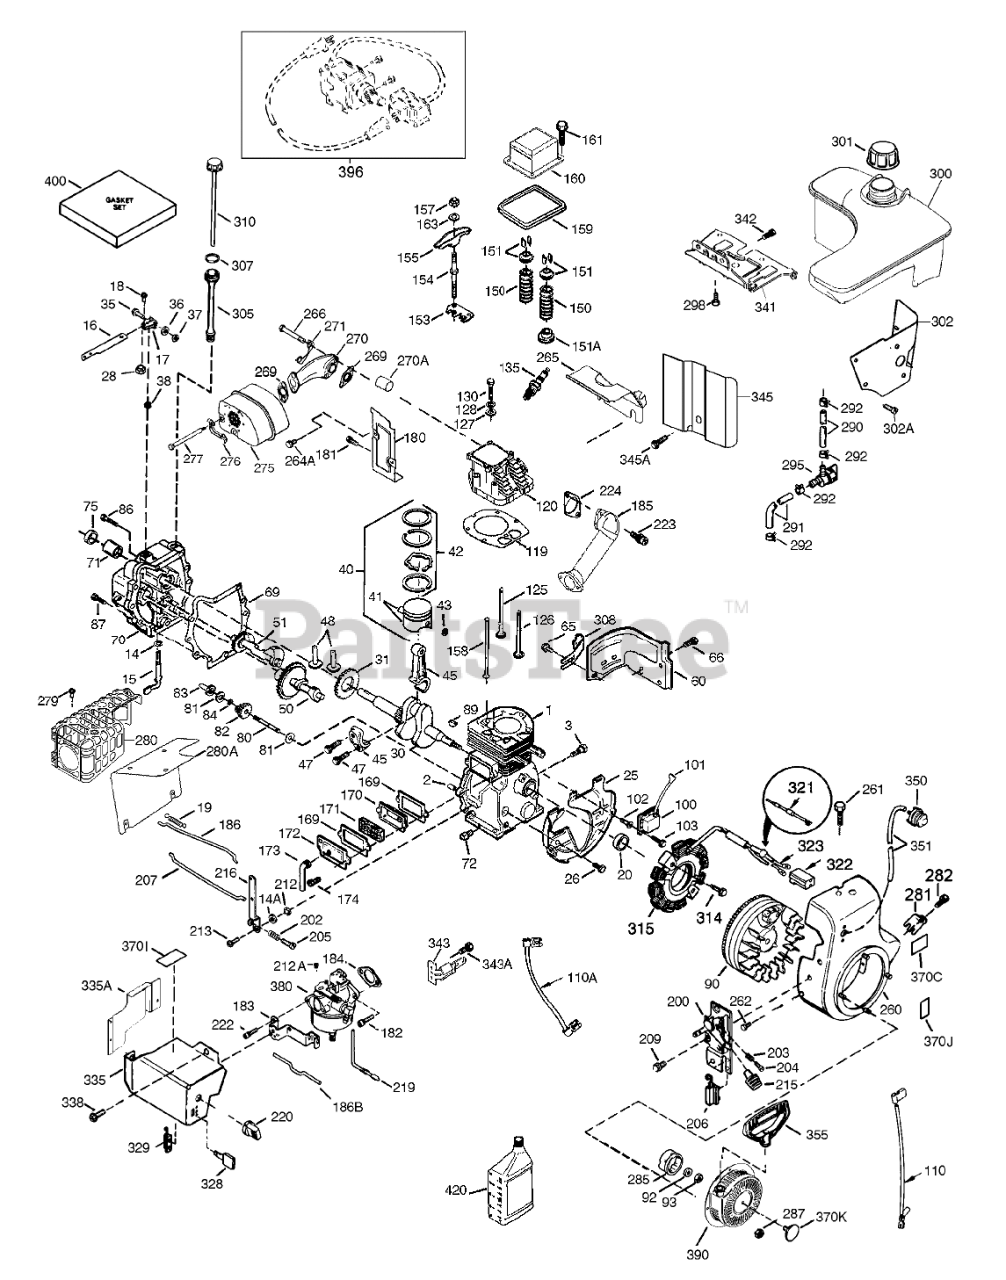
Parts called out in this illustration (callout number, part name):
1	Cylinder (Incl. 2, 20, 72 & 80)
2	Pin-Dowel
3	Screw (1/4-20x1/2)
14	Washer-Flat
14A	Washer
15	Governor Rod (Incl. 14 & 38)
16	Governor Lever (Incl. 212A)
17	Clamp-Lever, Governor
18	Screw (T-15, 8-32x7/16)
19	Throttle Spring
20	Seal-Oil
25	Baffle-Housing, Blower
26	Screw (1/4-20x19/32)
28	Nut-Lock
30	Crankshaft
31	Counterbalance Gear
35	Screw
36	Washer-Lock
37	Nut-Lock
38	Ring-Retaining
40	Piston Pin and Ring ASM (STD)
40	Piston Pin and Ring ASM (.010)
40	Piston Pin and Ring ASM (.020)
41	Piston & Pin Ass-y (Std.)(Incl. 43)
41	Piston & Pin Ass-y (.010" OS)(Incl. 43)
41	Piston & Pin Ass-y. (.020" OS)(Incl. 43)
42	Ring Set (STD)
42	Ring Set (.010)
42	Ring Set (.020)
43	Retaining Ring-Piston Pin
45	Connecting Rod ASM (Incl. 47)
47	Bolt-Rod, Connecting
48	Lifter-Valve
50	Camshaft
51	Counterbalance Weight
60	Extension-Housing, Blower
65	Screw (10-24 x 9/16)
66	Screw
69	55072/75/86/89 TWO
70	Cylinder Cover (Incl. 14, 15, 38, 71, 75)
71	Bushing-Crankshaft
72	Plug-Drain, Oil (SQH 1/4-18)
75	Seal-Oil
80	Governor Shaft
81	Washer
82	Gear-Asm Governor
83	Governor Spool
84	Ring-Retaining
86	Screw (1/4-20x1-3/16)
87	Screw (1/4-20x1-11/16)
89	Key-Flywheel
90	Flywheel (W/Ring Gear)
92	Washer-Belleville
93	Nut-Flywheel
100	Ignition-Solid State
101	Cover-Spark Plug
102	Stud-Mounting, Solid State
103	Screw (T-15, 10-24 x 15/16)
110	Wire-Ground
110A	Wire-Ground
119	Cylinder Head Gasket
120	Cylinder Head (Incl. 151A)
125	Valve-Exhaust (STD)
125	Valve-Exhaust (1/32)
126	Valve-Intake (STD)
127	Washer-Flat
128	Washer-Belleville
130	Screw (5/16-18 X 2-1/2)
135	Spark Plug-Resistor (R N 4C)
150	Spring-Valve
151	Keeper-Spring, Valve
151A	Cap-Spring, Valve
153	Guide-Rod, Push
154	Stud-Arm, Rocker
155	Arm-Rocker
157	Nut-Jam
158	Rod-Push
159	Gasket-Cover, Rocker Arm
160	Cover-Arm, Rocker
161	Screw
163	Washer
169	Gasket-Cover, Valve
170	Body-Breather
171	Element-Breather
172	Cover-Valve
173	Tube-Breather
174	Screw
180	Extension-Housing, Blower
181	Screw (10-24 x 9/16)
182	Screw (T-30, 1/4-20 X 27-32)
183	Bracket-Choke
184	Gasket-Carburetor To Intake Pipe
185	Pipe-Intake
186	Governor Link
186B	Spring-Choke
200	Control Bracket (Incl. 203 & 204)
202	Compression Spring
203	Spring-Compression
204	Screw (T-10, 5-40x7/16)
205	Screw
206	Terminal
207	Choke Link
209	Screw (10-32 x 1/2)
212	Bushing
212A	Bushing
213	Screw
215	Knob-Control
216	Lever-Adjusting
219	Rod-Choke
220	Knob-Control
222	Screw (10-32 x 1/2)
223	Screw (T-30, 5/16-18 X 7/8)
224	Gasket-Pipe
260	Housing-Blower
261	Screw (1/4-20 X 5/8)
262	Screw
264A	Screw
265	Cover-Head, Cylinder
266	Screw (5/16-18 X 1-9/32)
269	Gasket-Manifold, Exhaust
270	Manifold, Exhaust
270A	Liner-Port, Exhaust
271	Plate-Locking
275	Muffler
276	Plate-Locking
277	Screw (5/16-18 X 4-1/2)
279	Screw (10-32 x 1/2)
280	Shield-Heat
280A	Shield-Heat, Radiation
281	Screw
282	Screw (8-32 x 3/8)
285	Cup-Starter
287	Nut and Lock Washer (1/4-28)
290	Line-Fuel
291	Line-Fuel (8.62)
292	Clamp-Line, Fuel
295	Valve-Shut Off, Fuel
298	Screw (1/4-15x7/8)
300	Fuel Tank (Incl. 292 & 301)
301	Cap-Fuel
302	Extension-Tank, Fuel
302A	Screw (10-32 x 1/2)
305	Tube-Fill, Oil
307	O-Ring
308	Clip-Tube, Fill
310	Dipstick
314	Screw (1/4-20 x 3/4)
315	Alternator Coil (3/5)(Incl. 321-323)
321	Diode
322	Body-Connector
323	Terminal
328	Key-Ignition
329	Terminal
335	Spring
335A	Cover-Carburetor
338	Screw (10-32 x 1/2)
341	Bracket-Tank, Fuel
342	Screw (5/16-18 X 7/8)
343	Bracket-Switch, Key
343A	Screw (8-32 x 23/64)
345	Baffle-Heat
345A	Screw (10-32 x 1/2)
350	Primer ASM
351	Line-Primer
355	Handle-Starter, Mitten Grip
370C	Decal-Primer, International Symbol
370I	Decal-Warning (Bilingual)
370J	Decal-Choke
370K	Decal-Tecumseh Logo for Top of Recoil Starter
380	Carburetor (Incl. Ref.# 184)
390	Starter-Rewind
396	Electric Starter Motor (120 Volt)
400	Gasket Set
420	Oil-Engine, S A E 5W30
